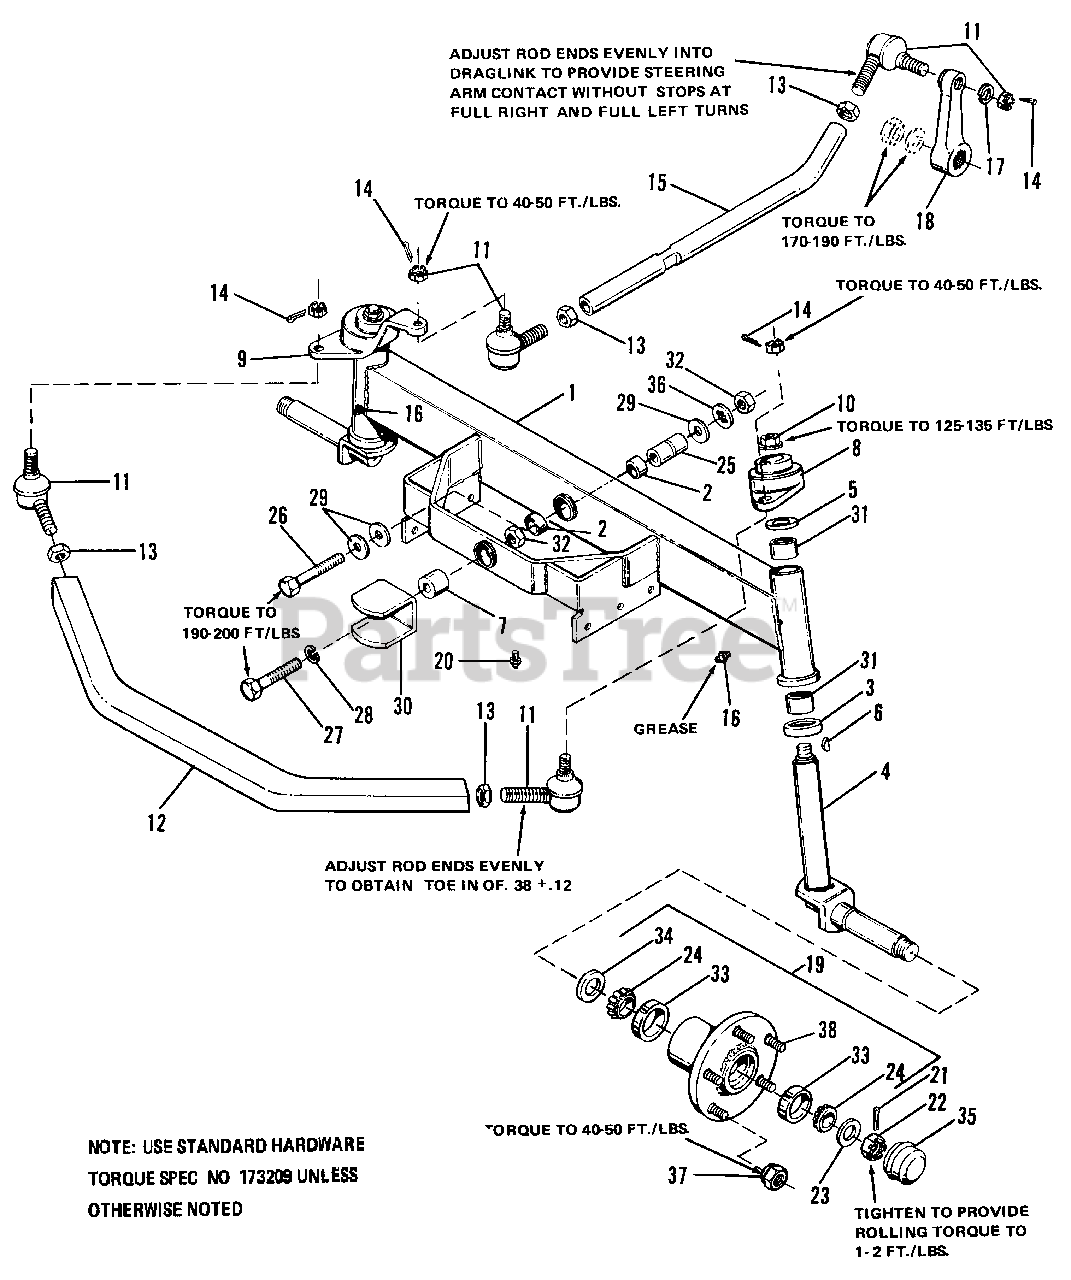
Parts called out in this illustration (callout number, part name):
1	AXLE ASSY
3	BEARING, Thrust
4	SPINDLE ASSY
5	WASHER, 1-1/8 I.D.-1-3/4 O.D.
6	KEY, Woodruff, No. 15, 1/4 x 1
7	BEARING, Reach
8	ARM, Steering, L.H.
9	ARM, Steering, R.H.
10	NUT, Lock, Flange, 3/4-16
11	JOINT, Ball, R.H.
13	NUT, Hex, Jam, 11/16-18
14	PIN, Cotter, 1/8-3/4
15	LINK, Drag
16	FITTING, Lube, 1/4-28
17	LOCKWASHER, 1/2
18	ARM, Pitman
20	FITTING, Grease
21	PIN, Cotter, 1/8 x 1
22	NUT, Hex, Jam, 3/4 16
24	BEARING, Cone
25	SPACER, Axle
26	CAPSCREW, Hex, 5/8-11 x 3-1/2
27	CAPSCREW, Hex, 5/8-11 x 2-3/4
28	LOCKWASHER, 5/8-11
29	WASHER, Thrust
32	NUT, Hex, Heavy
33	CUP, Bearing
36	LOCKWASHER, In-Tooth, 5/8
38	WHEEL, Bolt
